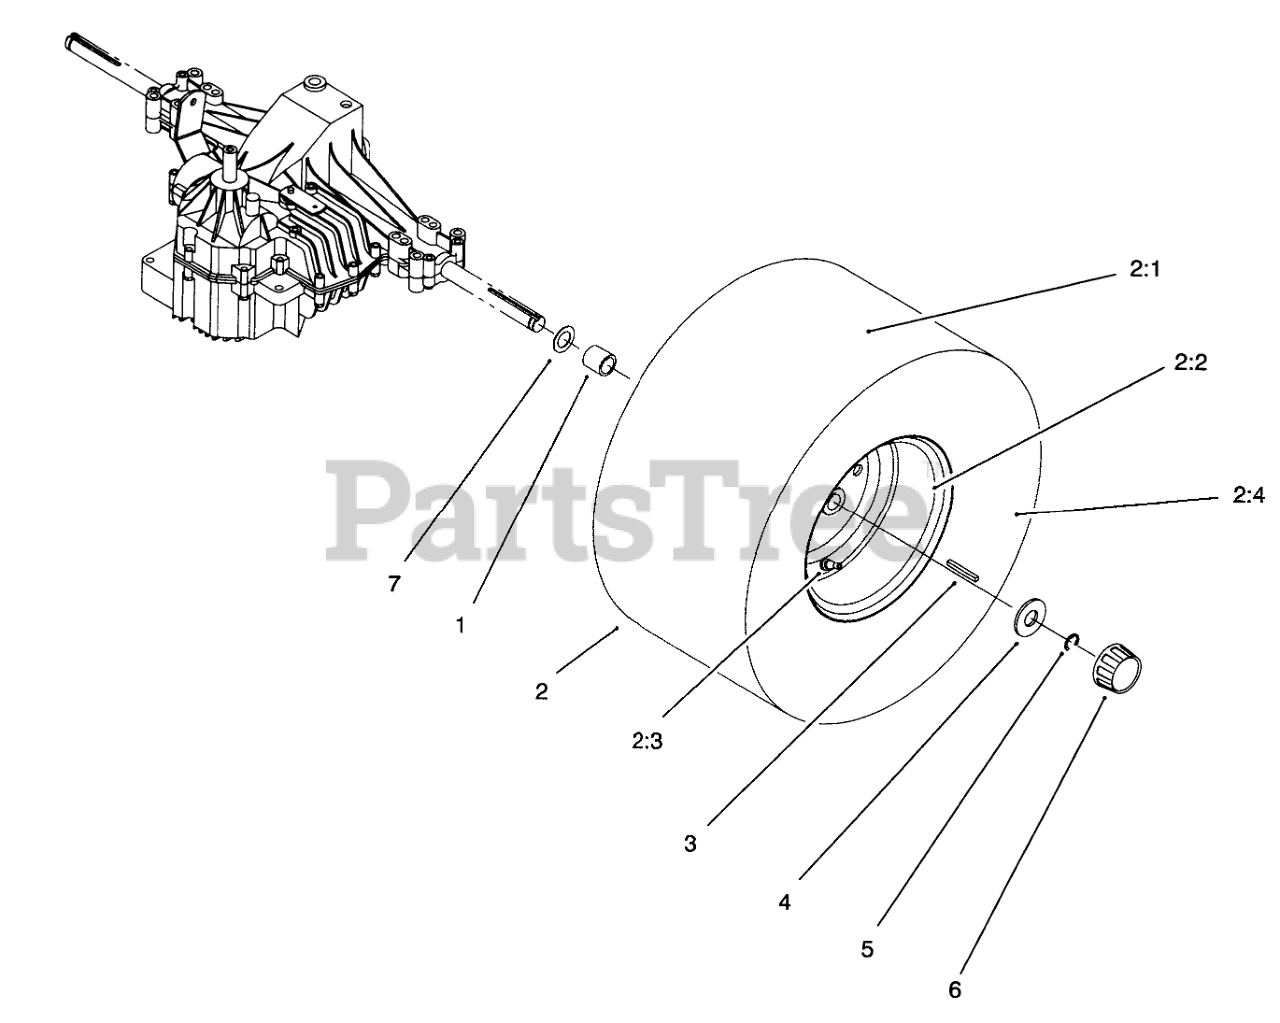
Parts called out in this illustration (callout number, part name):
1	SPACER
2:1	TIRE 20 INCH
2:3	STEM-VALVE
2:4	TUBE-INNER
3	KEY-SQUARE
4	WASHER-PLAIN
5	E-RING
6	CAP-HUB
7	WASHER-THRUST
